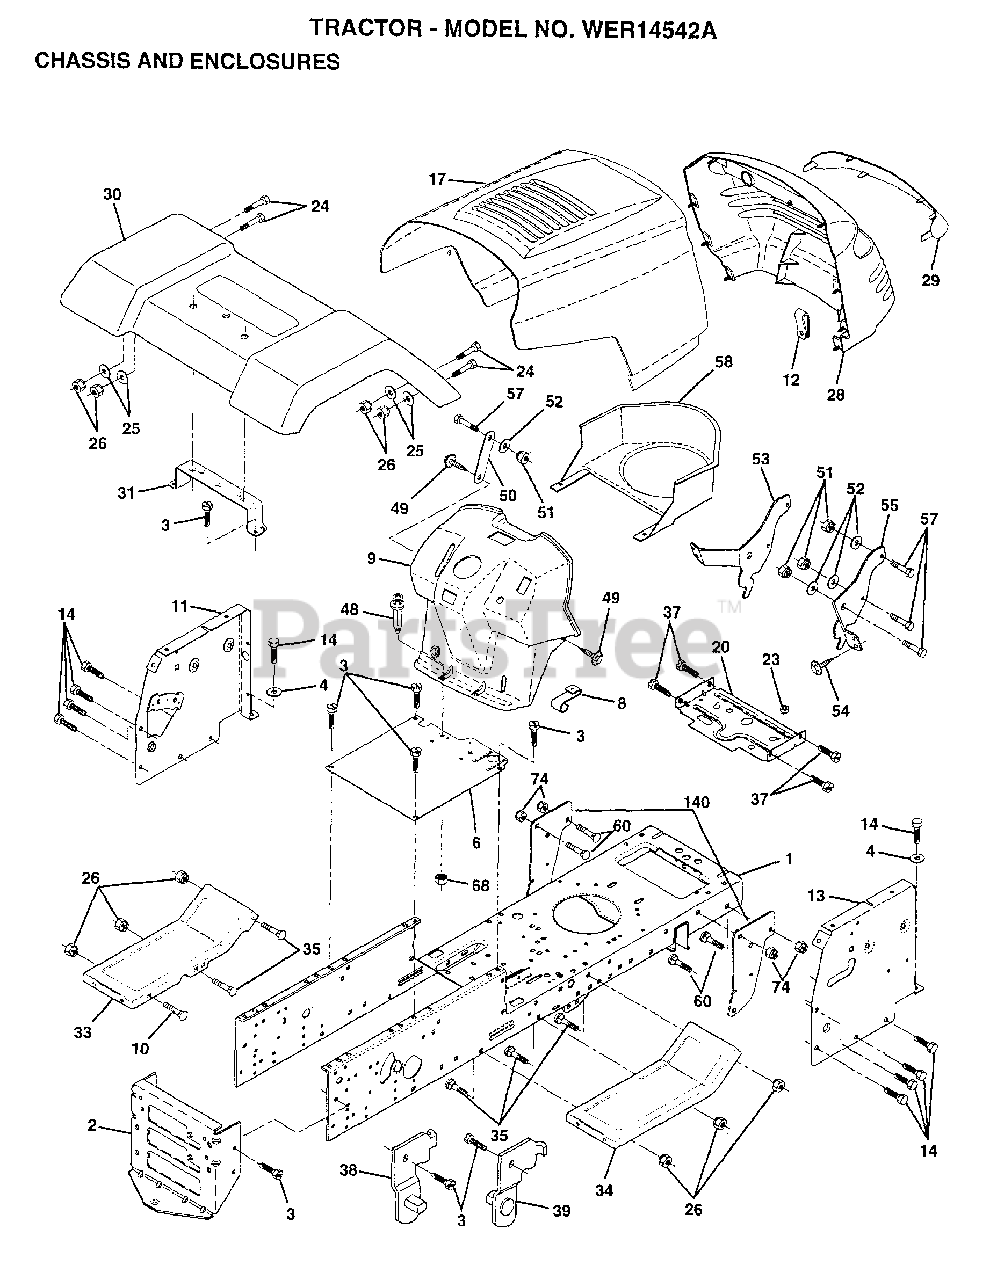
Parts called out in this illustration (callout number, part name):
1	CHASSIS WLDMT 11G
3	SCREW
4	WASHER
8	"CLIP,INSULATOR"
11	PANEL.DASH.LH.
12	CLIP.TINNERMAN
13	PANEL.DASH.RH
14	SCREW LT
20	PLATE.MTG.BTRY.TK
24	BOLT
25	WASHER
26	NUT
29	LENS GRILLE
31	BRKT FENDER
33	FOOTREST.LH.LT/GT
34	FOOTREST.RH.LT/GT
35	BOLT
37	SCREW LT
38	BRACKET ASM LH
39	BRACKET ASM RH
48	RIVET.PUSH.PLATE
49	SCREW HEX CRT
50	BRACE SUPT DASH
51	NUT
52	WASHER
53	BRACKET.GRILLE.LH
55	BRACKET.GRILLE.RH
58	AIR DUCT
60	BOLT
68	NUT
